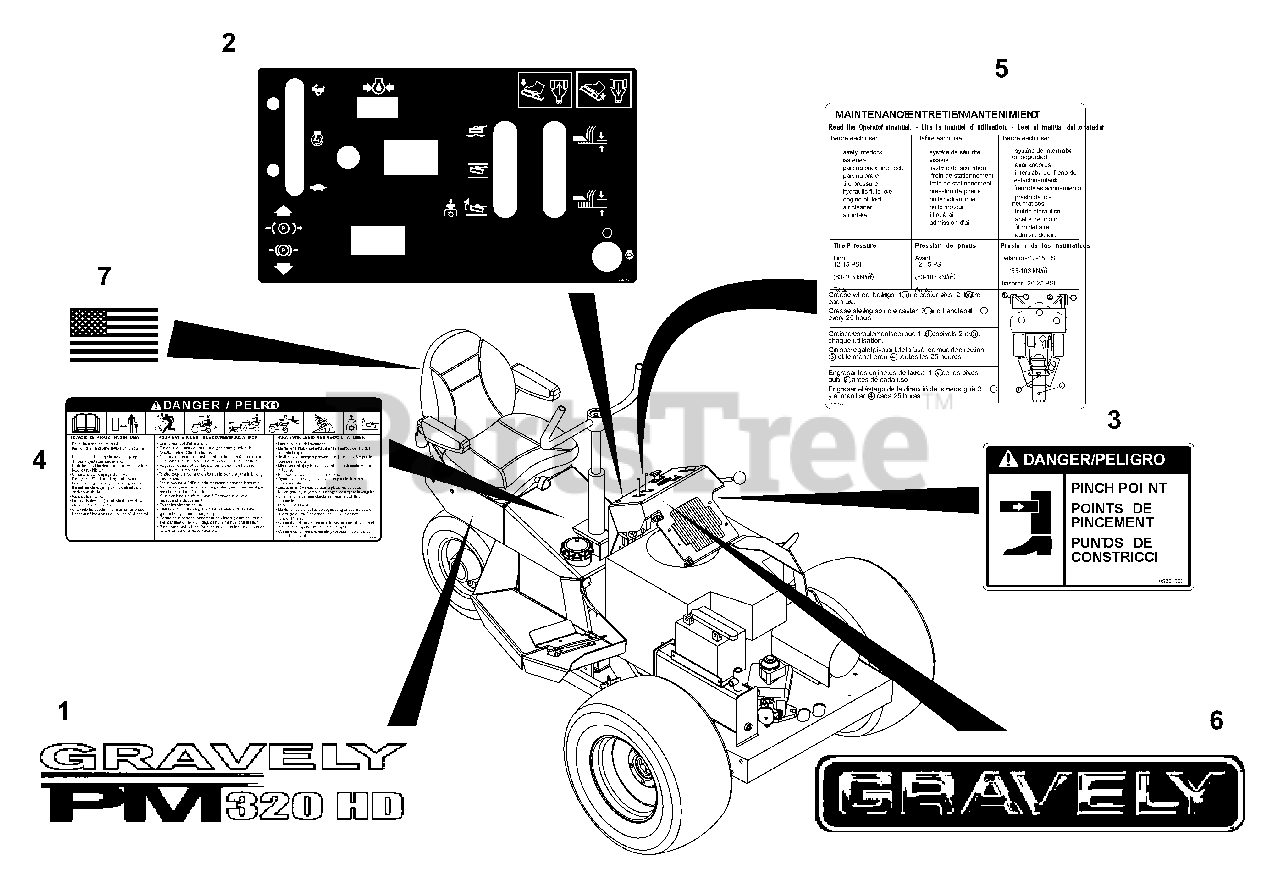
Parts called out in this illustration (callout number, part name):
1	Decal, PM-320
2	Decal, PM-310 Panel
3	Decal, Pinch Point
4	Decal, PM-310 Danger
5	Decal, PM-310 Maintenance
6	Decal, Gravely Logo
7	Decal, American Flag
